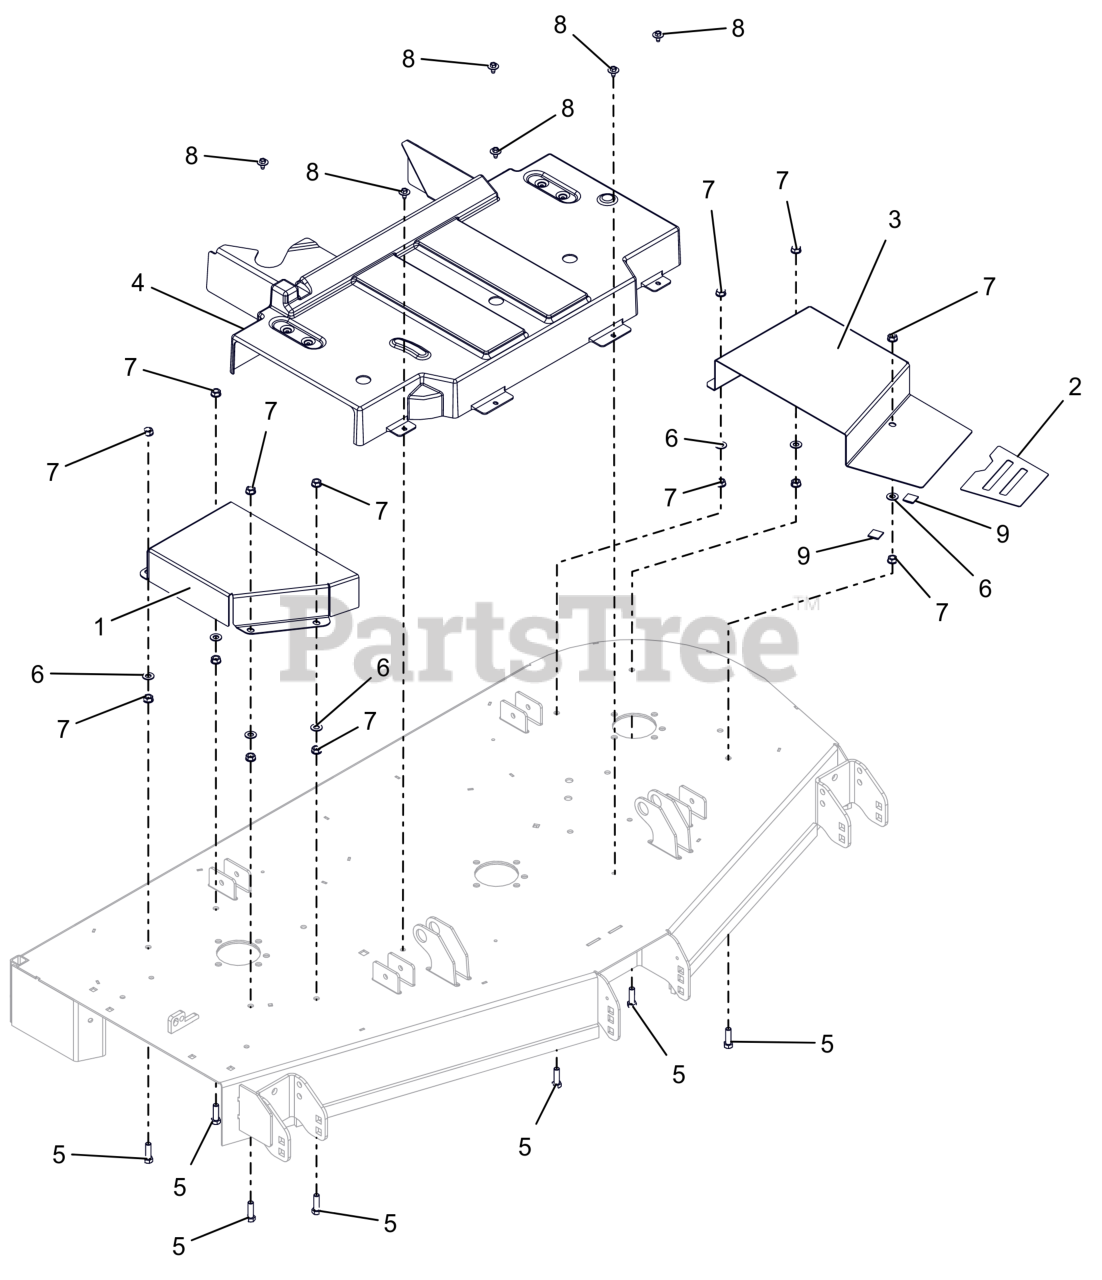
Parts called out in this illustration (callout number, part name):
1	GUARD,BELT 52" RIGHT CE
2	GRIP TAPE 52-60 BELT COVER
3	GUARD, BELT 60" LEFT CE (ORANGE)
4	GUARD, CENTER DECK SPINDLE CE
5	BLT, HEX .38-16X1.25 G5 ZCC
6	WSHR,FLT .406X.812X.065 ZCC
7	NUT, SPNLK-FLG .38-16 G5 ZCC
8	SCR, TAP .25-20X.50 LG HWH ZCC
